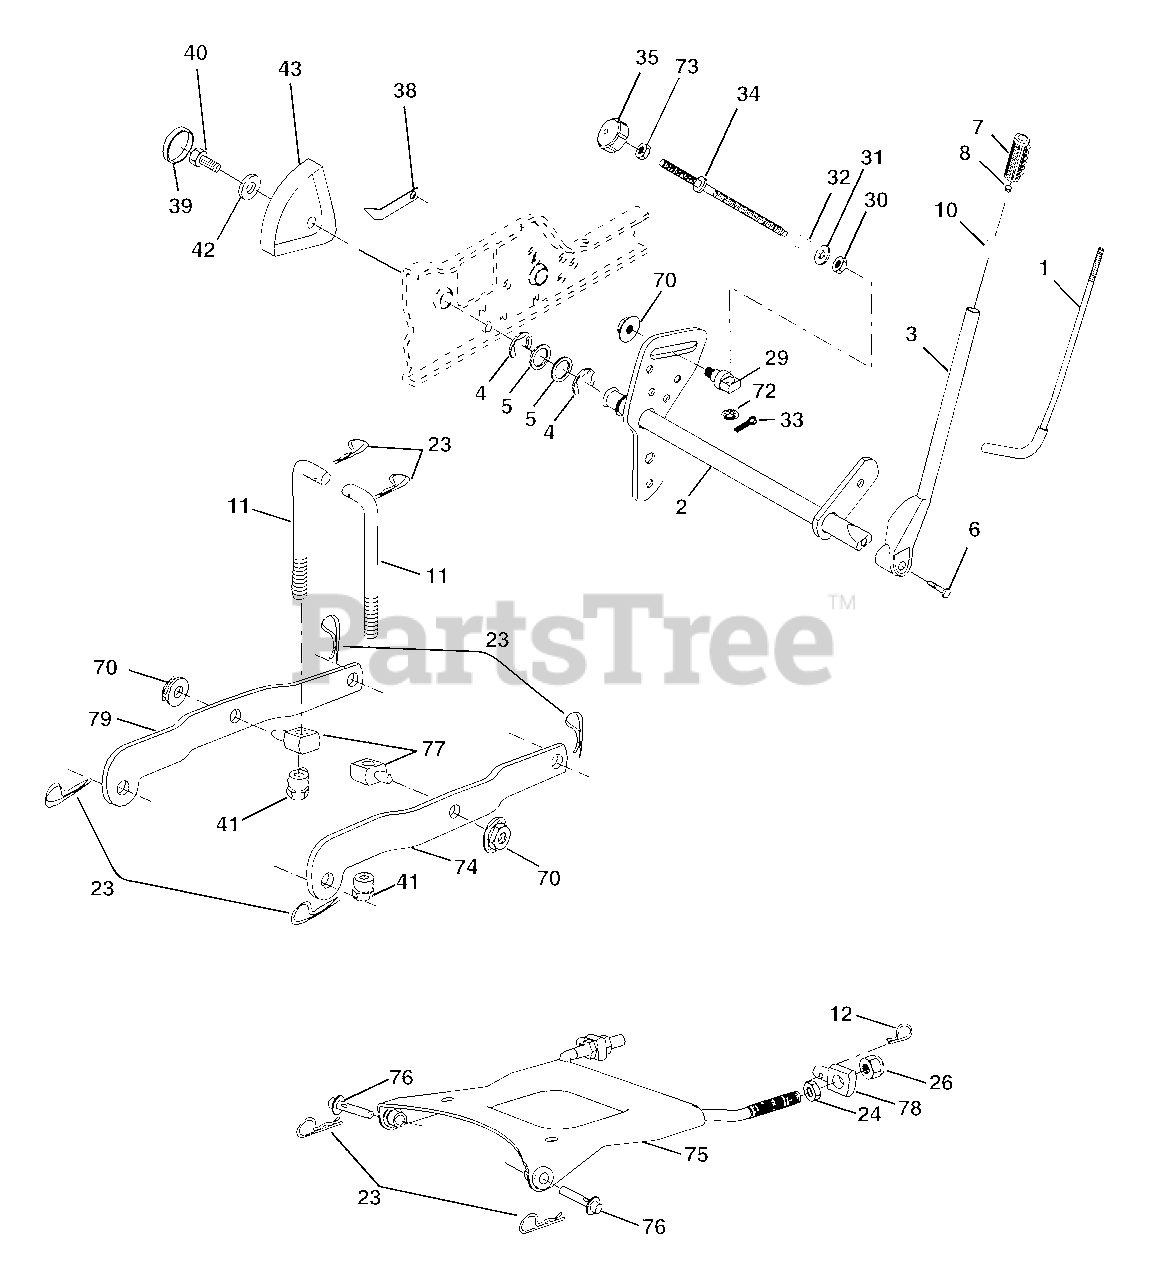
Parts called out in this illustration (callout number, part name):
1	Rod Asm., Lever
2	Shaft Asm., Lift Vgt
3	Lever Asm., Lift Rh
4	E-Ring Truarc #5133-87
5	Washer 29/32 x 1-1/4 x 16 Ga.
6	Bolt, Fin Hex 3/8-16 x 1-1/2
7	Grip, Handle
8	Button, Plunger
9	Plunger, Lever Lift
10	Spring 0.62 OD x 2.125
11	Link Lift
12	Retainer, Spring
23	Retainer, Spring
24	Nut, Jam Hex 1/2-13 Unc
26	Nut, Crownlock 1/2-13 Unc
29	Trunnion Inf. Height
30	Nut, Special
31	Washer 13/32 x 5/8 x 16 Ga.
32	Spring, Compression Inf Hgt
33	Pin, Cotter 3/32 x 1/2
34	Rod, Adj Lift
35	Knob, Inf 3/8-16 Unc
38	Pointer, Height Indicator
39	Plug, Hole
40	Screw 5/16-18 x 3/4
41	Nut, Lift Link 7/16-20
42	Washer 11/32 x 1-1/2 x 10 Ga.
43	Scale, Indicator Height
70	Nut, Hex flange Lock
72	Nut, Push Phos & Oil
73	Nut Hex Jam 3/8-16 Unc
74	Arm Susp. Rear RH
75	Plate Asm Susp. Front
76	Pin Flange
77	Trunnion Susp. Arm
78	Trunnion Susp. Front
79	Arm Susp. Rear LH
